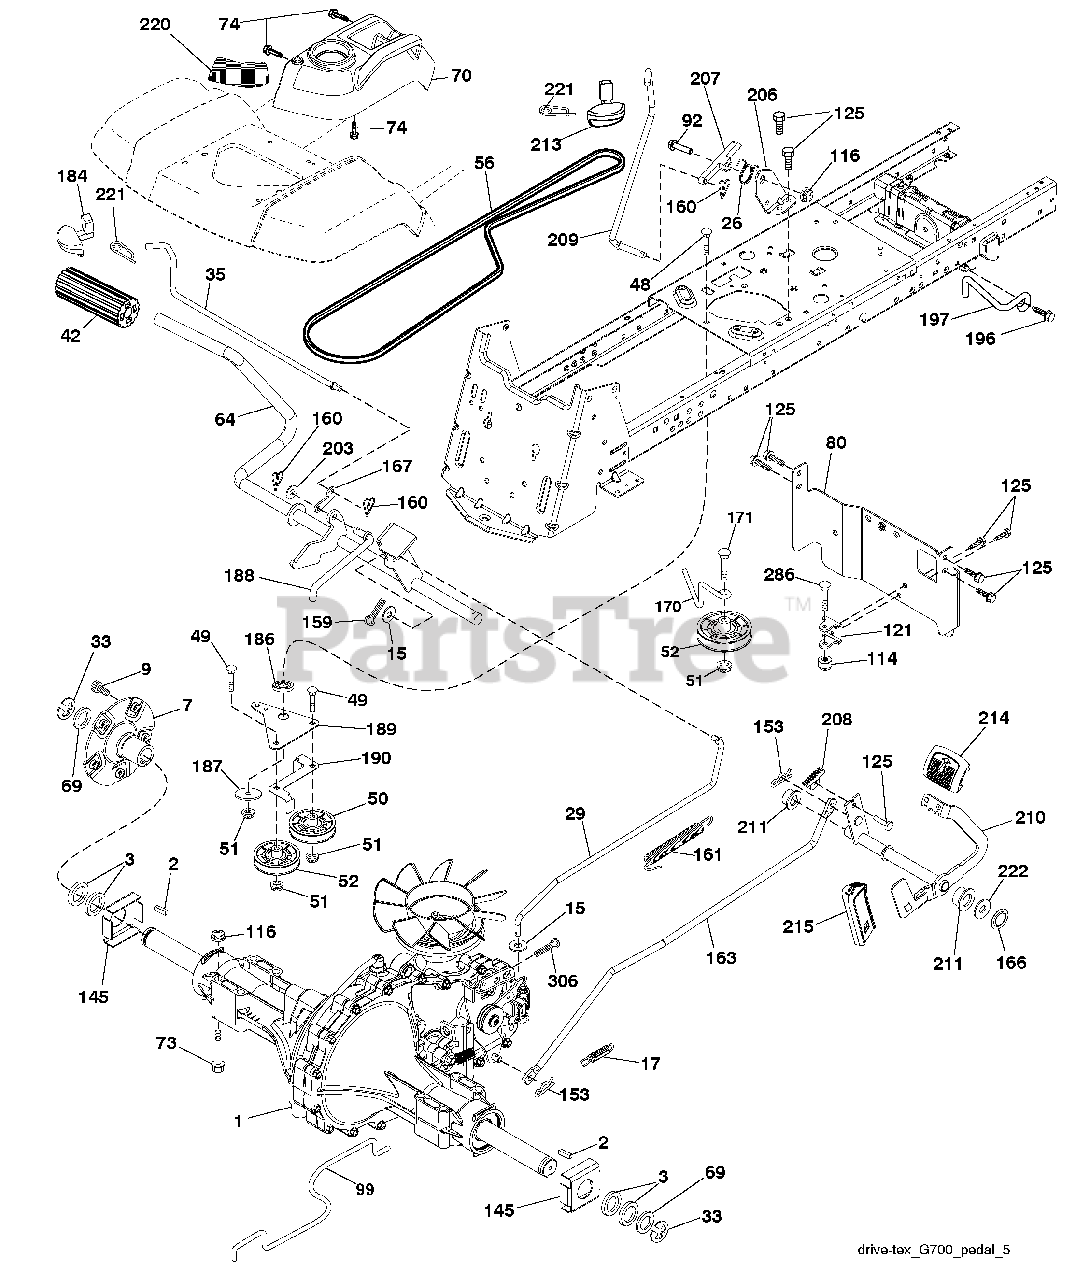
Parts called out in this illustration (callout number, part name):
2	Key 1/4 x 2.5
3	Washer Thrust Axle Hardened
7	Hub Asm. Wheel
9	Bolt Hub Wheel
15	Washer 13/32 x 13/16 x 16 Ga.
17	Spring, Brake
26	Spring Return Cruise
29	Rod, Brake
35	Rod, Brake, Park
42	Cover, Foot Pedal
48	Bolt Carr Sh 3/8-16 x 1-1/2 Gr.5
50	Pulley Idler Flat
51	Lock Nut 3/8-16
52	Idler V-Groove 910" Offset
56	V-Belt, Drive
64	Shaft Asm. Pedal Brake Control
69	Washer 1-1/32 x 1-5/8 x 16 Ga.
70	Console Asm
73	Bolt Hex 5/16-18 x 3 Gr. 5
74	Screw 1/4 x 1/2
80	Strap Torque
92	Bolt 5/16-18 x 1/2
99	Spring Bypass
114	Nut Lock Hex W/Ins. 5/16-18 unc
116	Nut Lock Hex Flange 5/16-18
121	Bracket Strap Torque
125	Screw 5/16-18 x 3/4
145	Washer Axle Flange
153	Retainer Spring
159	Pin Cotter 1/8 x 3/4
160	Retainer Clip
161	Spring, Return, Clutch
163	Rod Pedal Control
166	Nut Push .625
167	Latch Brake Parking
170	Keeper V-Idler Center Span
171	Bolt RD HD SQNK 3/8-16 x 2
184	Handle Parking Brake
186	Spacer Retainer
187	Washer
188	Link Clutch Ground Drive
189	Bellcrank Ground Drive
190	Keeper Bellcrank Ground Drive
196	Screw 3/8-16 x 1
197	Bracket Clutch Anti-Rotation
203	Washer 11/32 x 11/16 x 16 Ga.
206	Bracket Mount Latch Cruise
207	Latch Control Cruise
208	Gear Sector Control Cruise
209	Rod Control Cruise
210	Rocker Asm. Pedal Control
211	Bearing Nylon
213	Knob Control Cruise
214	Pedal Forward
215	Pedal Reverse
220	Reflector RH
221	Retainer Spring Clip Handle
222	Washer 21/32 x 1-1/4 x 10 Ga.
286	Bolt 5/16-18 x 2.50
306	Pin Cotter 1/8 x 1
